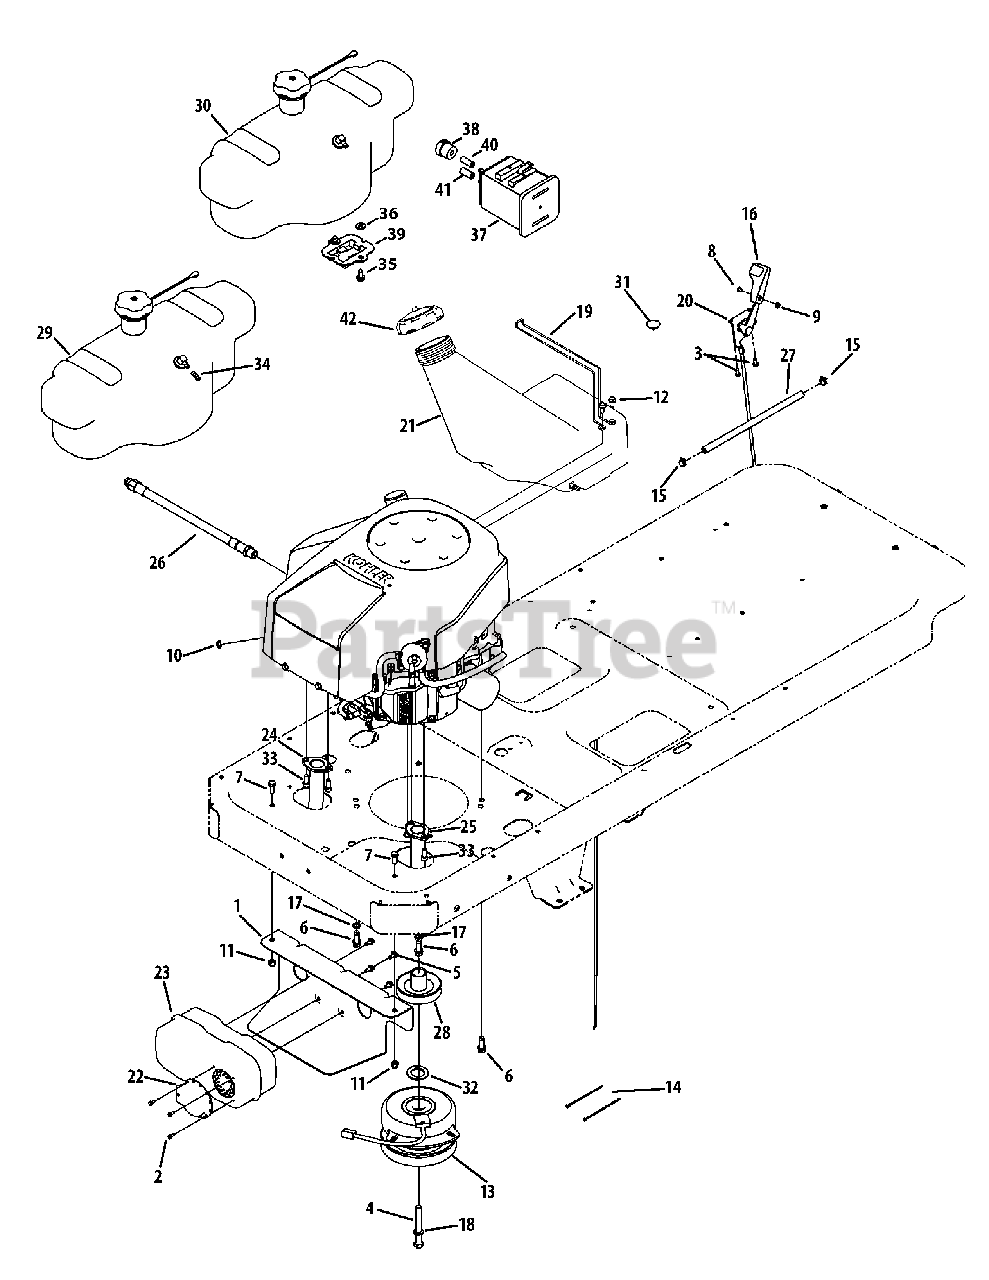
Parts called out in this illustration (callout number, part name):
1	Muffler Mount Bracket
2	Hex Washer Screw, #8-18 x .500
3	Screw, 1/4-14 x .625
4	Hex Screw, 7/16-20 x 3.25
5	Hex Washer Screw, 1/4-20 x .500
6	Hex Washer Screw, 3/8-16 x 1.000
7	Hex Washer Screw, 5/16-18 x .75
8	Machine Screw, #8-32 x .375
9	Hex Nut, #8-32
10	Sems Nut, 1/4-20
11	Flange Lock Nut, 5/16-18
12	Hex Washer Screw, 5/16-18 x .750
13	Electric PTO Clutch
14	Cable Tie
15	Hose Clamp
16	Throttle Control Knob
17	Lock Washer, 3/8
18	Lock Washer, 7/16
19	Tank Wire
20	Throttle/Choke Control Cable
21	Fuel Tank
22	Muffler Deflector
23	Dual Inlet Muffler
24	Exhaust Pipe, LH
25	Exhaust Pipe, RH
26	Oil Drain Hose
27	Fuel Hose
28	Engine Pulley
29	Fuel Tank Assembly
29	Fuel Tank Bushing
29	Fuel Pick-Up Fitting
29	Fuel Tank
29	Fuel Cap
30	Fuel Tank Assembly
30	Fuel Tank Bushing
30	Rubber Grommet
30	Fuel Tank
30	Fuel Pick-Up Fitting
30	Fuel Cap
30	Rollover Valve
31	Choke Plug
32	Flat Washer, 1.03 x 1.620 x .095
33	Screw, 5/16-18 x .750
34	Hose Vent, 3/16 EPA
35	Screw 5/16-18 x .875
36	Washer, Flat, .344 x .750 x .120
37	Canister, Carbon, 5 Gallon
38	Filter, Vent, Canister
39	Bracket., Adapter, Canister
40	Hose, Fuel, Low Perm., White
41	Hose, Fuel, Low Perm., Yellow
42	Fuel Cap
